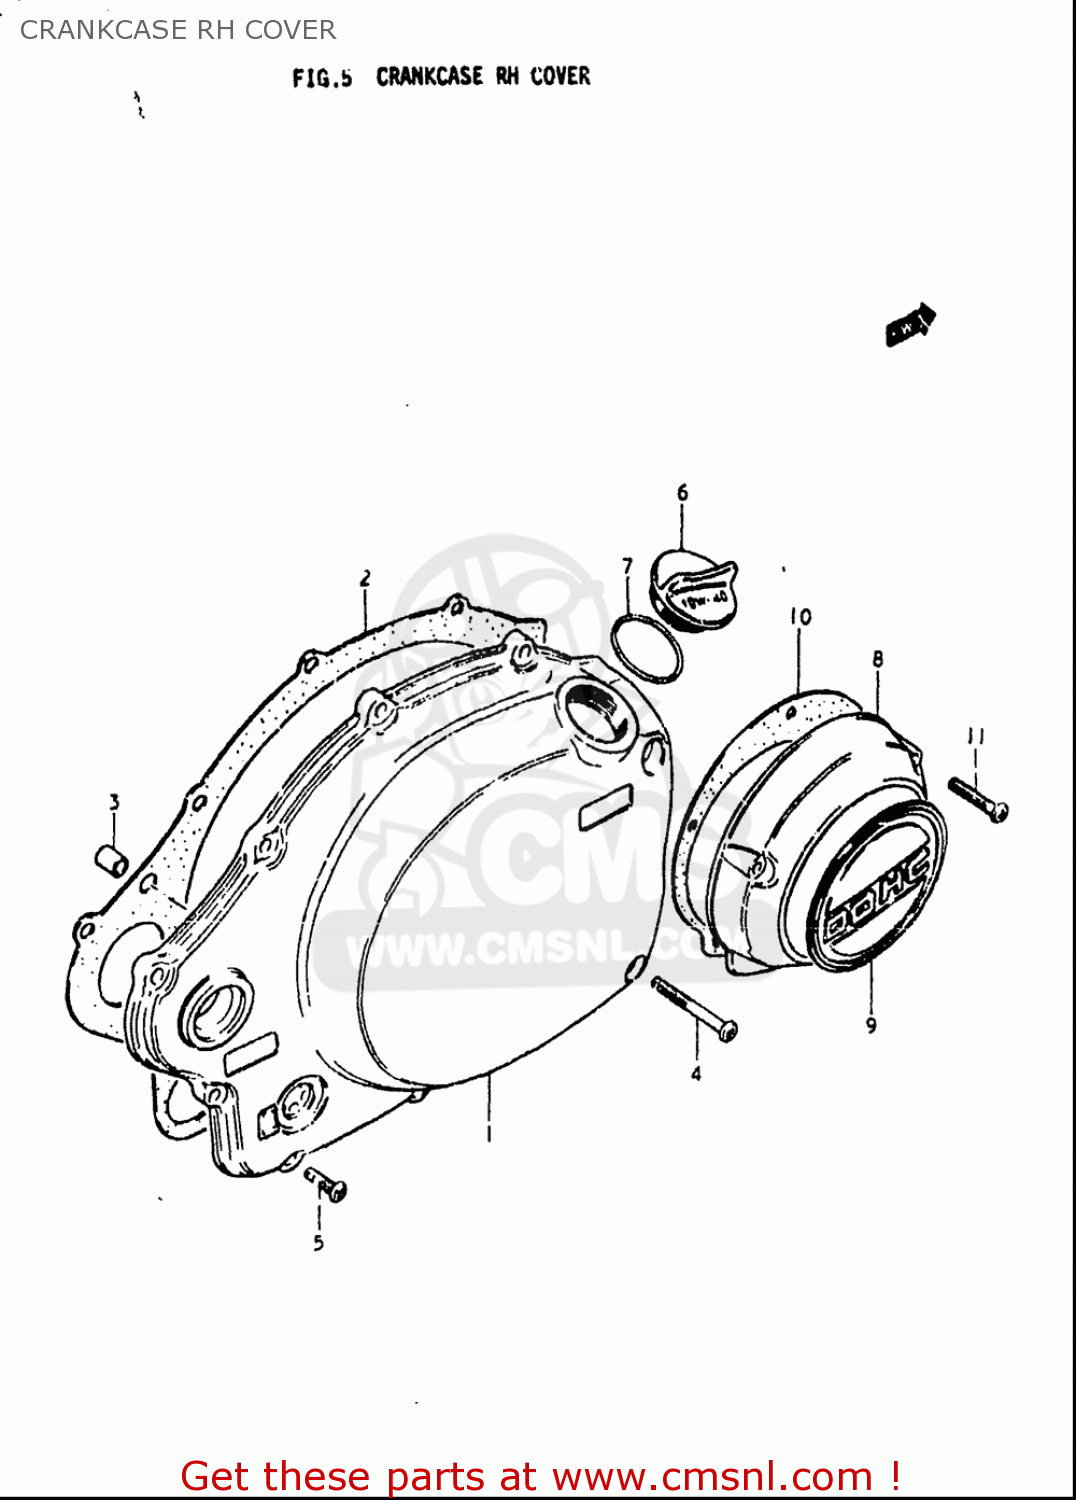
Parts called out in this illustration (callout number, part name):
2	GASKET,CLUTCH COVER (NAS)
3	PIN
4	SCREW
5	SCREW
6	PLUG SET
7	O RING(D:2.2,ID:32)
8	COVER,CONTACT BREAKER
9	EMBLEM,CONTACT BREAKER COVER
10	GASKET,CONTACT BREAKER COVER (NAS)
11	SCREW
